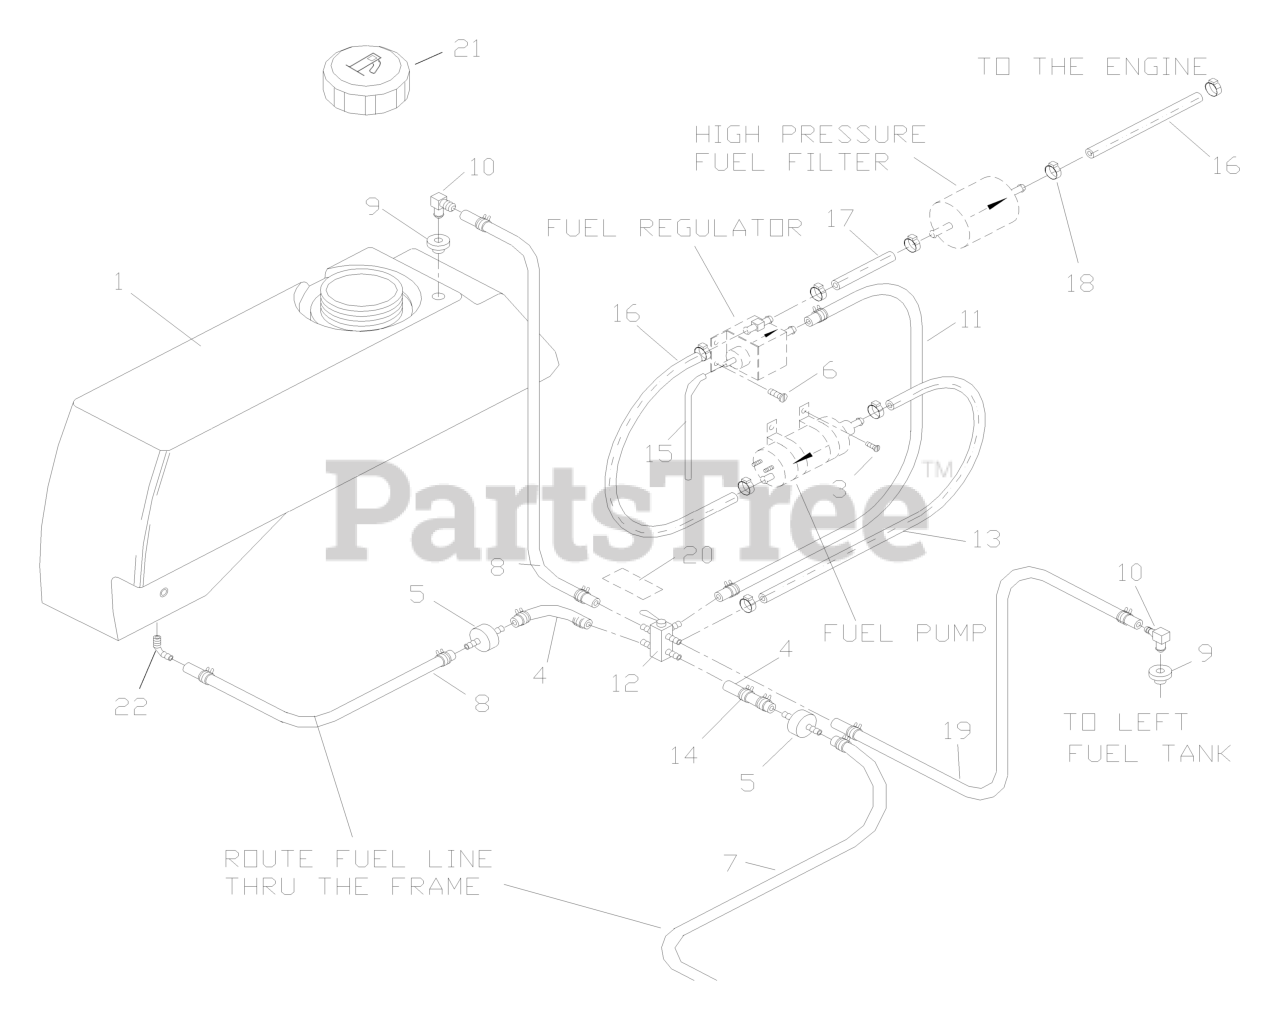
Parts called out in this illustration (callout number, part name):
1	FUEL TANK DIESEL RT
2	FUEL TANK DIESEL LT
3	SCREW #10 X 1/2 SELF TAPPING
4	GAS LINE 3 1/2"
5	FUEL FILTER
6	HEX CAP SCREW 1/4
7	FUEL LINE 29.5"
8	FUEL LINE 18"
9	RUBBER GROMMET
11	FUEL LINE 24"
12	FUEL VALVE
13	EFI HOSE - 18"
14	HOSE CLAMP
16	EFI HOSE - 8"
17	EFI HOSE - 4"
19	FUEL LINE 34"
20	FUEL VALVE DECAL
21	FUEL CAP ANTI-SPLASH
22	HOSE BARB 90 DEGREE
